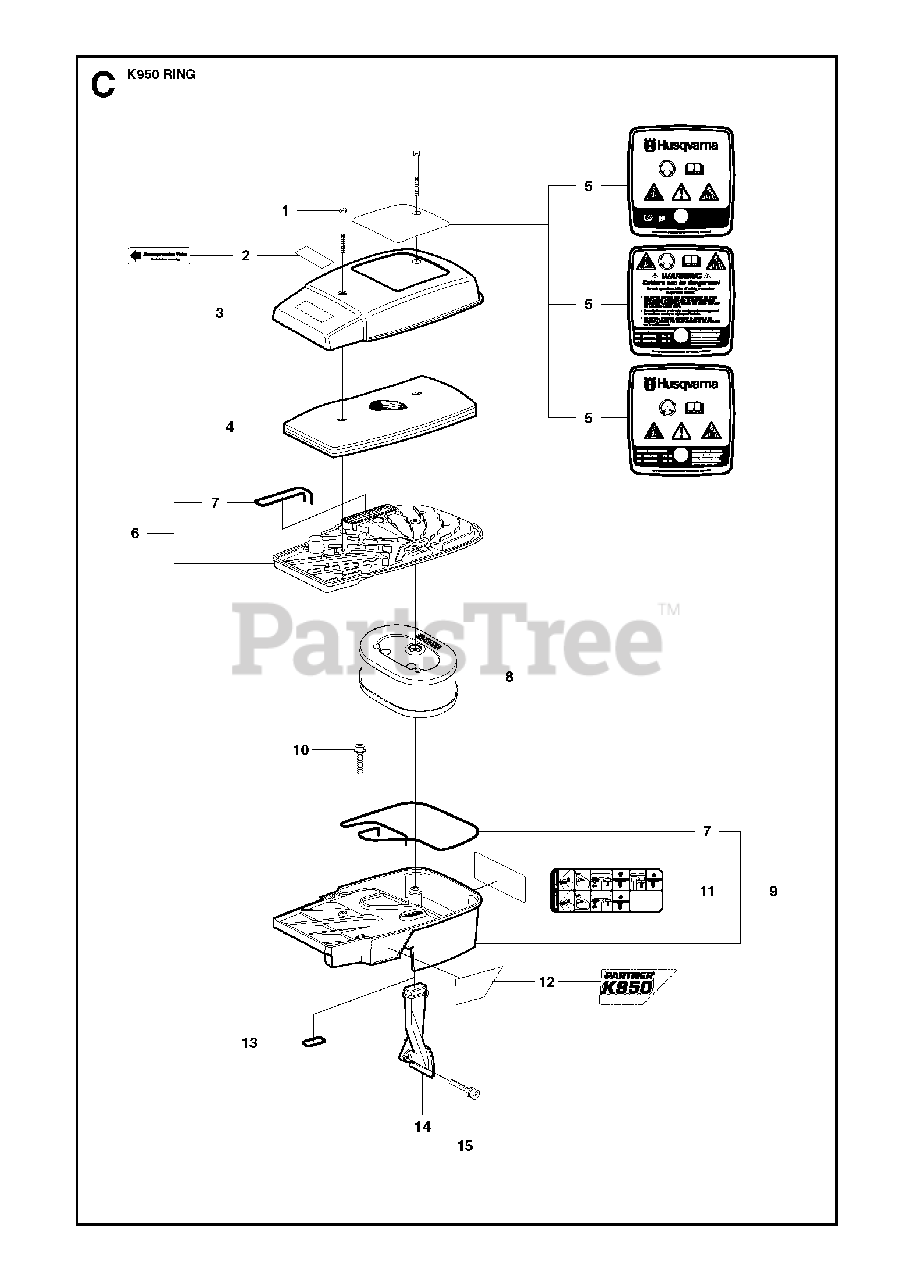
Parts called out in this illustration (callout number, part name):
3	COVER
5	LABELEPA USA
5	LABELEPA Canada
6	FILTER BOTTOMIncl. 7
9	CYLINDER COVER ASSYIncl. 7, 10, 11, 12
10	SCREW IHSCFM
12	LABEL
15	SCREW IHSCFM
